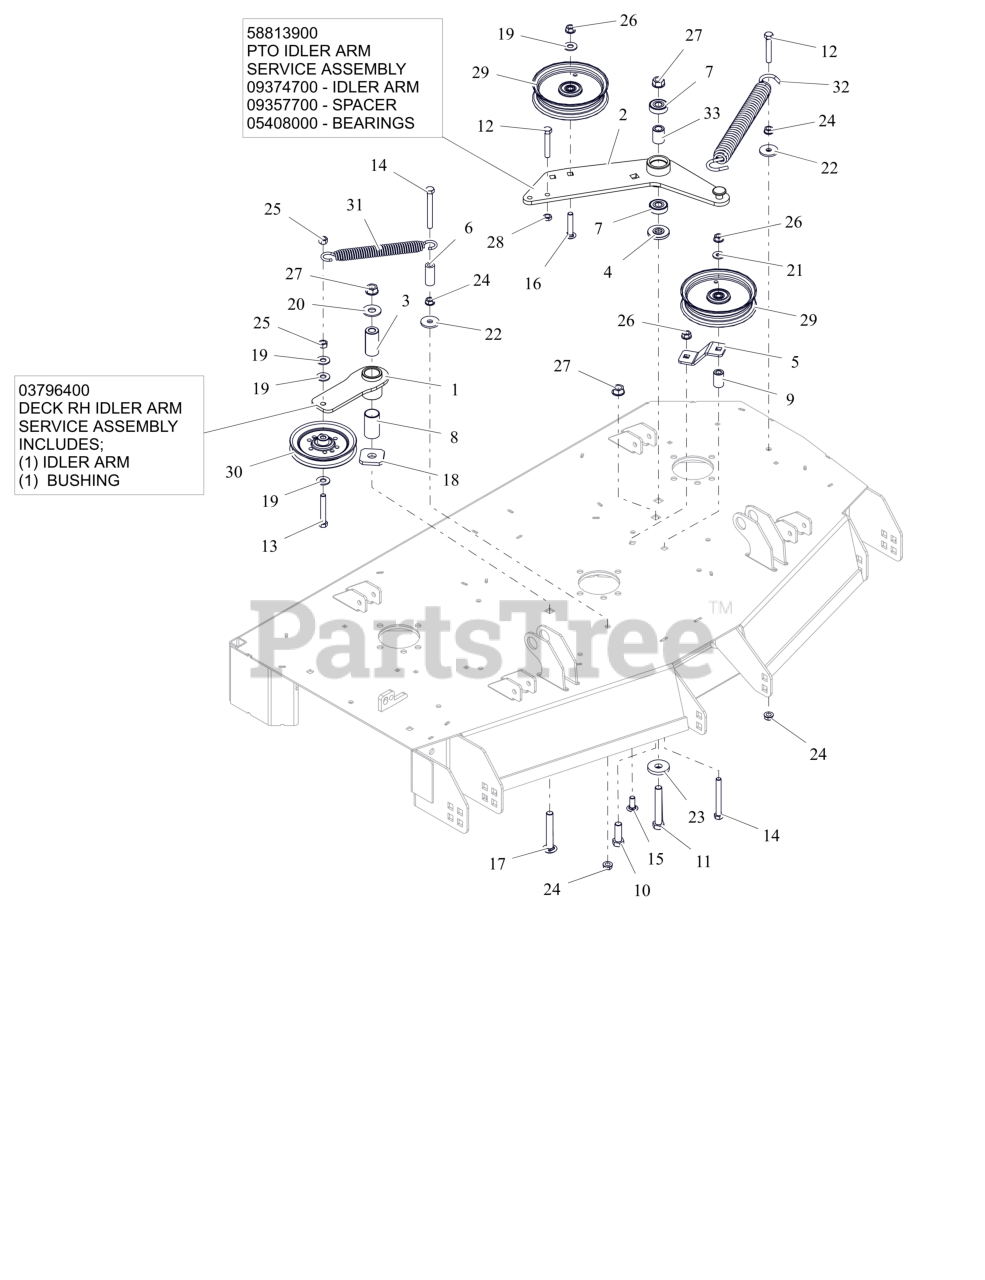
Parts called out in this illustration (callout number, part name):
1	WMT, IDLER ARM - BLACK
1	ASM, IDLER ARM (DECK)
2	WLDMT, IDLER ARM PT660
2	PTO IDLER ARM
2	SPACER .510 X .867 X 1.1485
2	BRG-BALL .500X1.38X.437
3	BSHG, SPCR .502X.997X2.03 PM
4	SPACER, IDLER ARM
5	PTO FIXED IDLER MTG BRKT -RED
6	HOSE, .38 X 1.65
7	BRG-BALL .500X1.38X.437
8	BSHG, 1.00X1.125X1.937
9	BUSHING, SLV .380X.750X1.190
10	BLT,HEX .50-13X1.50 G5 ZCC
11	BLT,HEX .50-13X3.25 G5 ZCC
12	BLT,HEX .38-16X2.25 G5 ZCC
13	BLT, HEX .38-16X2.50 G5 ZCC
14	BLT, HEX .38-16X3.25 G5 ZCC
15	BLT,RHSSN .38-16X1.00 G5 ZCC
16	BLT,RHSSN.375-16X2.00 G5 ZCC
17	BTL,RHSSN .500-13 X 3.25 G5 ZCC
18	WSHR-FLT .640X1.75X.250
19	WSHR,FLT .438X1.00X.083 ZCC
20	WSHR,FLT .563X1.375X.109 ZCC
21	WSHR,FLT .375X.875X.083 ZCC
22	WSHR,FLT .406X1.375X.135 ZCC
23	WSHR-FL-STL 0.557X1.625X0.25 ZCC
24	NUT, SPNLK-FLG .38-16 G5 ZCC
25	NUT-LK-CTR .38-16 ZC120
26	NUT-LK-CTR-FLG .375-16 GF ZCC
27	NUT-LK-CTR-FLG .500-13 GG ZCC
28	NUT-JAM .375-16 G2 ZCC
29	IDLER- FLAT - 5.00" X .75"
30	IDLER, V, 5.00X.38
31	SPRING- EXTENSION
32	SPRING, EXTENSION
33	SPACER .510 X .867 X 1.1485
